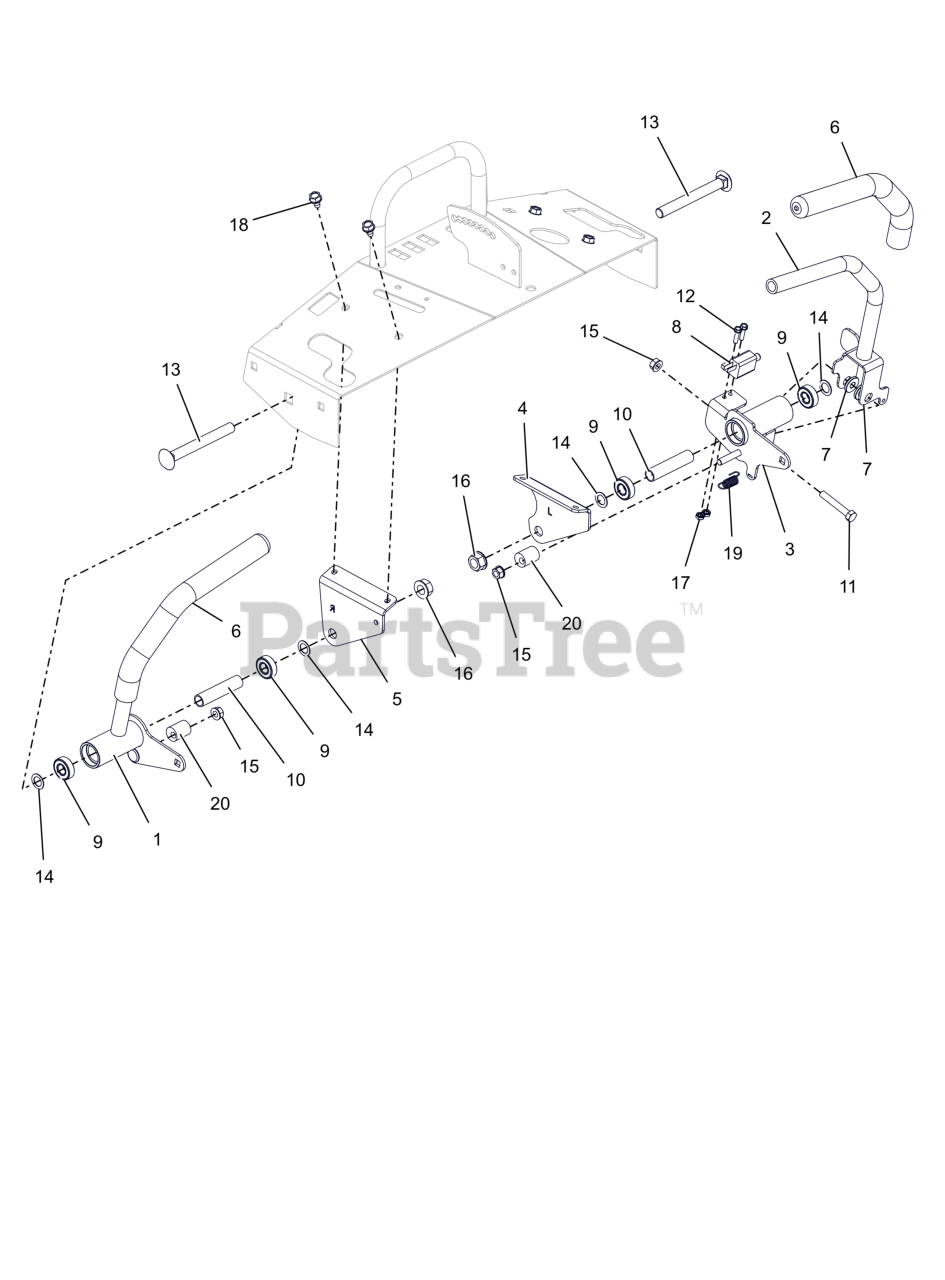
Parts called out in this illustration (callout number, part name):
1	WLDMT, RH DRIVE CONTROL (BLACK)
2	WLDMT, LH HANDLE ASM (BLACK)
3	WLDMT, LH DRIVE CONTROL (BLACK)
4	BRKT, LH DRIVE CONTROL MTG
5	BRKT, RH DRIVE CONTROL MTG
6	GRIP, HANDLEBAR
7	BSHG, FLG .325X.499X.26X.88
8	SWITCH- SINGLE POLE N.O.
9	BEARING, .500X1.125X.375
10	SPCR, .510 X .625 X 2.75
11	BLT, HEX .31-18X2.00 G5 ZCC
12	BLT, HWH #10-24X.75 ZCC
13	BLT,RHSN .50-13X4.50 G5 ZCC
14	WSHR-FL-STL 0.52X0.81X0.033 ZCC
15	NUT,LK-CTR-FLG .31-18 GF ZCC
16	NUT-LK-CTR-FLG .500-13 GG ZCC
17	NUT-KEPS 10-24
18	SCR,TAP .312-18X.50 HWH TR ZCC
19	SPRING, EXT. .043X.438X1.64
20	ECCENTRIC
